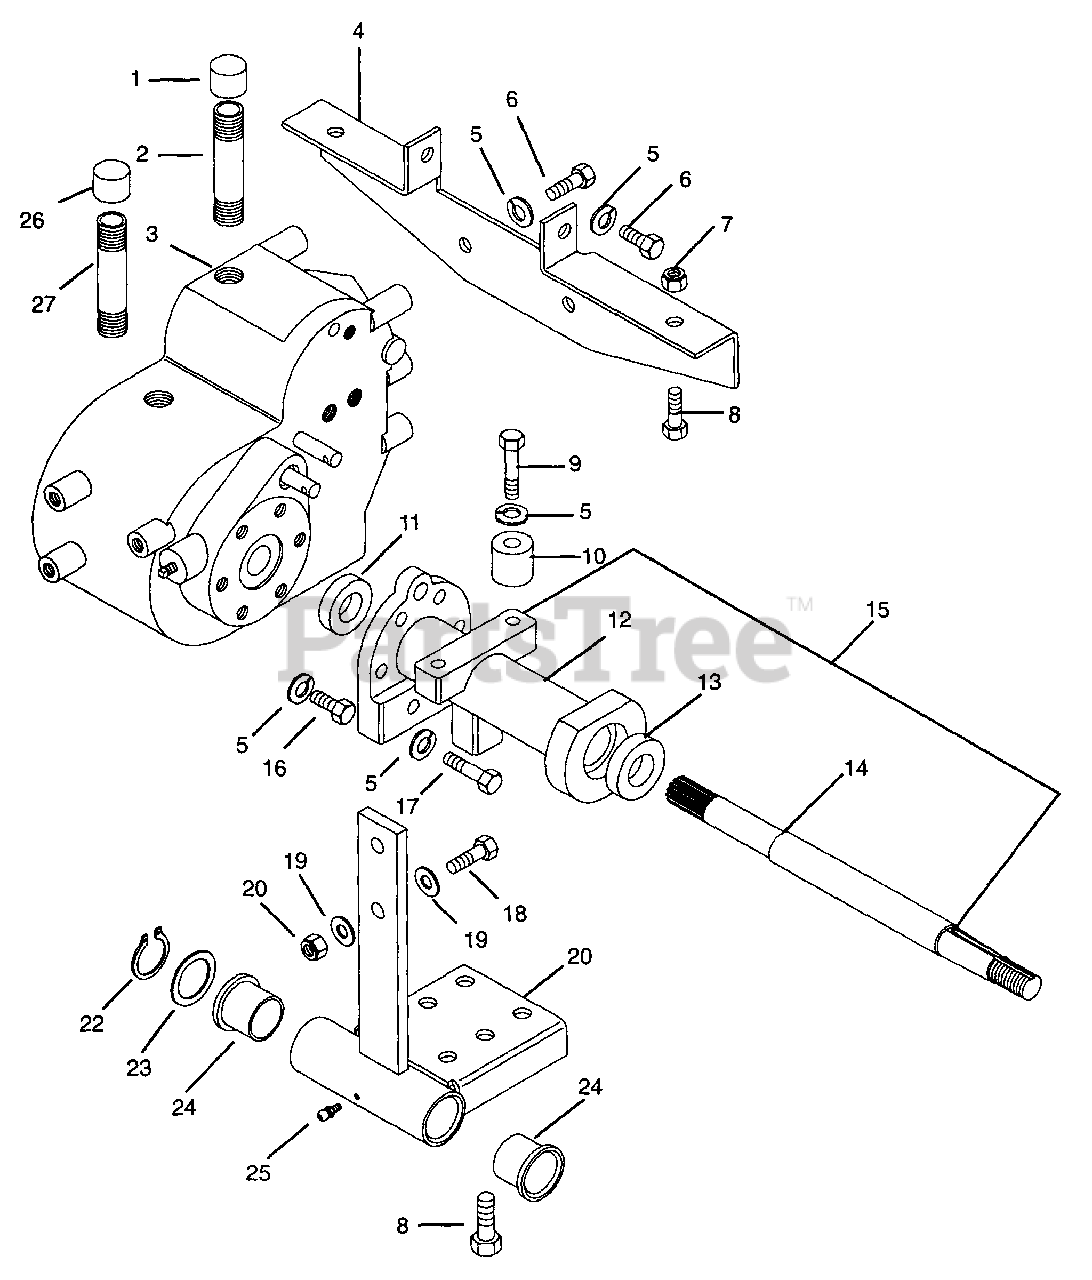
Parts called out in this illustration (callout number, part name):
1	Plug, Breather 1/2 IN NPT
2	Pipe, Reducing .75 X 5.0
3	Transaxle
4	Plate, Transaxle
5	Washer-Locking .50 X .125
6	Bolt-Hex .50-13 x 1.25 Grade 5
7	Nut-Locking-Center .62-11
8	Bolt-Hex .62-11 x 1.50
9	Bolt-Hex .50-13 x 2.75 Grade 5
10	Spacer, Frame
11	Ring, Alignment
12	Housing, Axle
13	Bearing, Ball 1.181 x 2.440 x .629
14	Axle, w/Taper
15	Assembly, Axle Housing
16	Bolt-Hex .50-13 x 1.50 Grade 5
17	Bolt-Hex .50-13 x 2.25 Grade 5
18	Bolt-Hex .375-16 X 1.5 Grade 5
19	Washer-Flat-Steel .531 x 1.06 x .095
20	Weldment, Pivot Bracket
21	Nut-Locking-Center .50-13
22	Ring-Retaining-external 1.5 x 1.38
23	Washer-Thrust 1.502 x 2.18 x .063
24	Bushing-Flange 1.514 x 1.756 x 1.688 x 2.250
25	Fitting-Lube .25-28 x .256
26	Pipe Cap
28	Plug, Breather 1/2 IN. NPT
